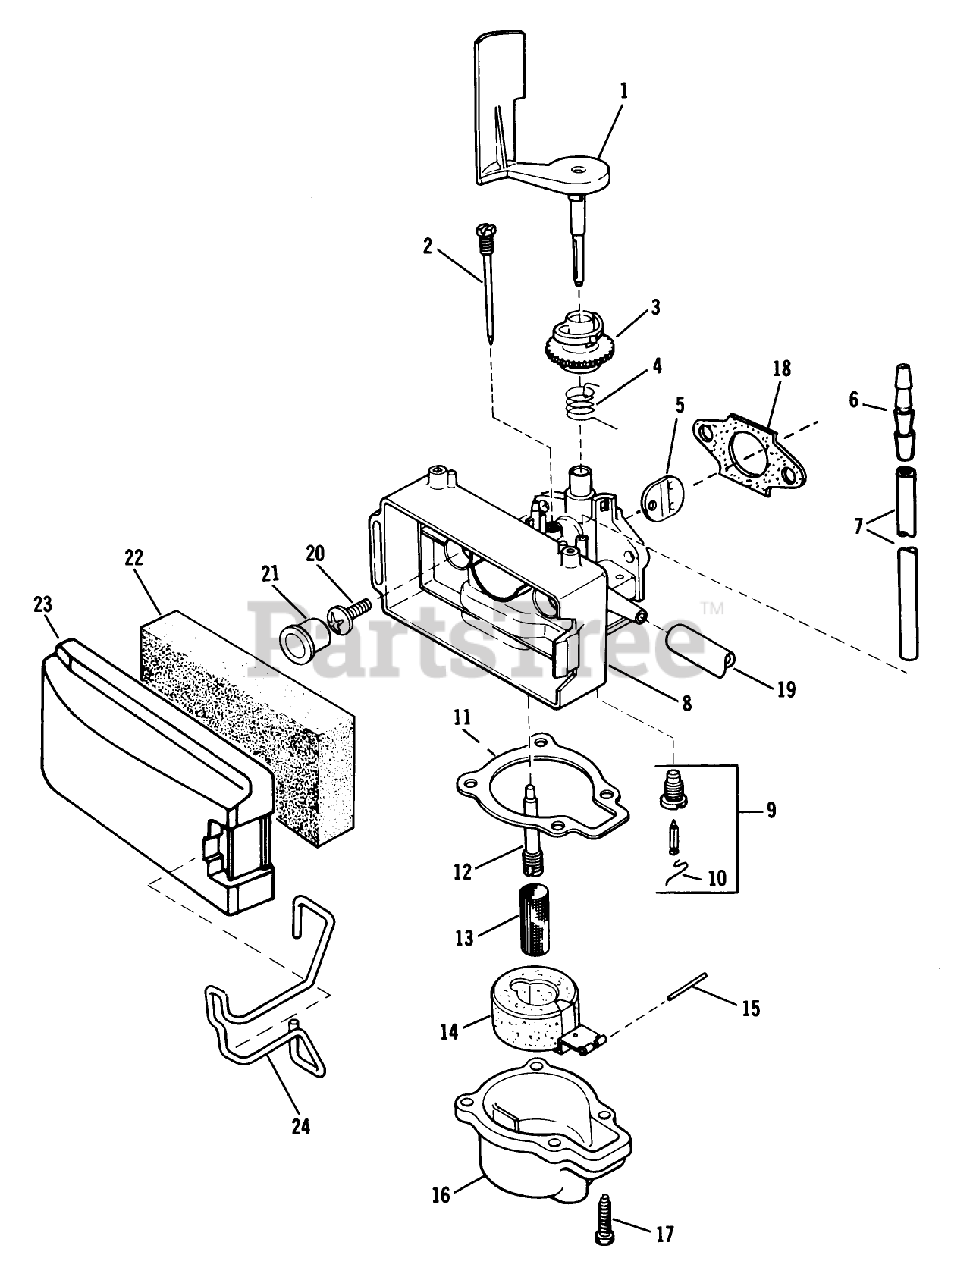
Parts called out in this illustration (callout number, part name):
2	NEEDLE ADJ. AY S
3	COLLAR-ADJUST, AIRVANE
4	SPRING-THRO. S
5	DISC S
6	REDUCER-CONNECTOR
7	TUBING S
8	CARB BODY S
13	FILTER-FUEL VS
17	SCREW-HH
18	GASKET CARB S
19	GAS LINE
20	SCREW
24	RETAINER-COVER, FILTER
